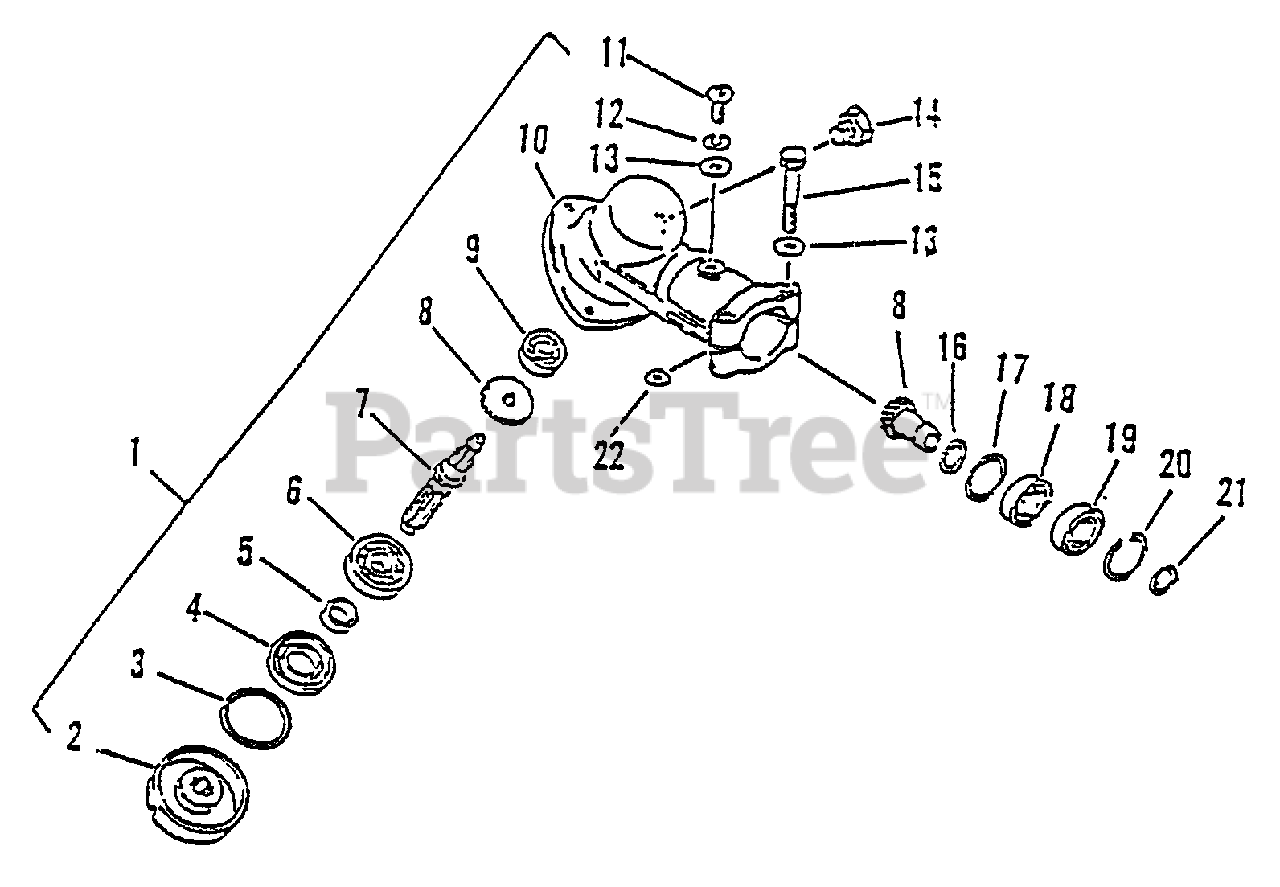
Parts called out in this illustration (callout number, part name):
1	GEAR CASE ASSY
2	ADAPTOR, BLADE - UPPER
3	RING, RETAINING - 32
4	SEAL, OIL
6	BEARING, BALL - 6201
7	GEAR - SHAFT
8	GEAR SET - BEVEL
9	BEARING, BALL - 609
10	CASE, GEAR
11	SCREW - 5X10
12	LOCKWASHER - 5
13	WASHER - 5
14	BOLT - 8X8
15	BOLT - 5X35
18	BEARING, BALL - 6900
19	BEARING, BALL - 6900Z
20	RING, RETAINING - 22
21	RING, RETAINING - 12
